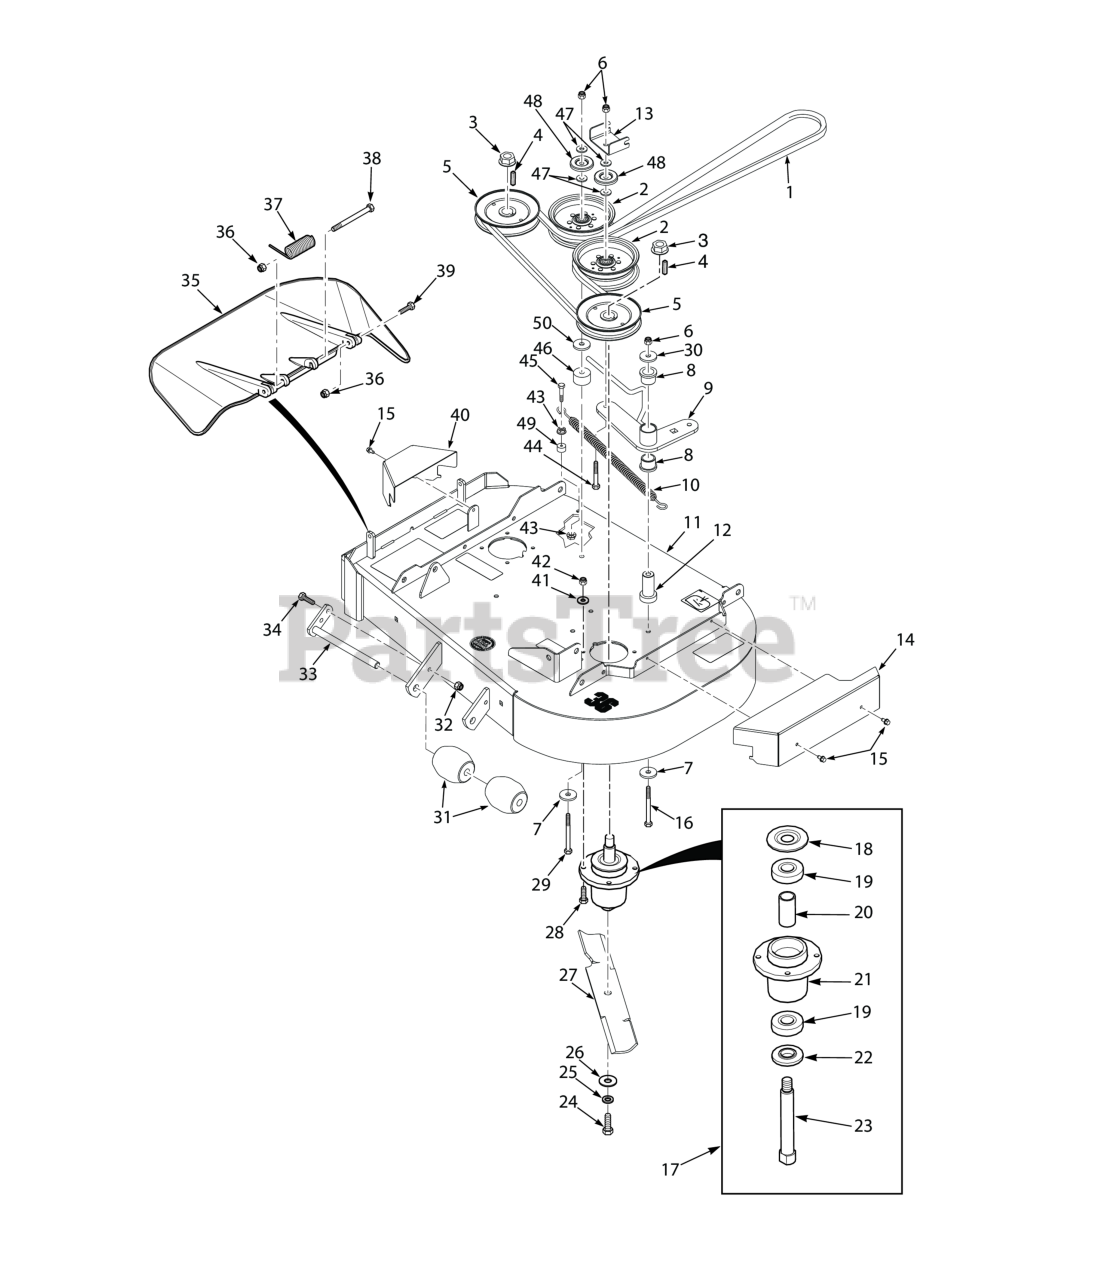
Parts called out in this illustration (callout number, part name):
1	Belt, Cutter Deck
2	Pulley, 5" Idler
3	Nut, 3/4-16 Spriral Lock
4	Key, 1/4 x 1/4 x 1.25" Pulley Mtg.
5	Pulley, 5.73" OD - 25mm Bore
6	HEX NUT, ELASTIC STOP LOCK, 3/8-16
7	Flatwasher, 3/8-.406 x 2.25" x .1875
8	Bearing, Plastic
9	Pivot, Idler
10	Spring, Cutter Deck Idler
11	Cutter Deck w/Decals, SWZT36H
12	Pivot, Idler
13	Bracket, Belt Guide
14	Belt Cover LH SMZL-36
15	Screw, 1/4-20 x .375"
16	Bolt, Hex Head 3/8-16 x 4.00
17	Spindle Assembly
18	Debris Shield
19	Bearing
20	Spacer, Bearing
21	Spindle Housing Assembly
22	Protector, Bearing
23	Shaft, Spindle
24	Bolt, Hex Head 5/8-11 x 1-1/2"
25	Lockwasher, 5/8" Spring
26	Flatwasher, 5/8-.688 x 1-3/4 x .134 HD
27	Cutter Blade, 18" (52V)
28	Bolt, Hex Head 5/16-18 x 1-1/2" Grade 8
29	Bolt, Hex Head, 3/8-16 x 3-1/2"
30	Flatwasher, 3/8-.406 x 1-1-1/2 x 7 Gauge
31	Wheel, Anti-Scalp
32	Nut, Flange Head Elastic Stop 5/16-18
33	Shaft Weldment, Guide Roller
34	Bolt, Heax Head 5/16-18 x 1" (48V / 52V)
35	Discharge Chute Assy. SFZ48
36	HEX NUT, ELASTIC STOP LOCK, 5/16-18
37	Spring, Discharge Chute
38	Bolt, 5/16-18 x 4-3/4" Hex Head
39	Bolt, Hex Head 5/16-18 x 1-1/2" - Front
40	Belt Cover, RH SMZL-36
41	Lockwasher, 5/16 (.317 x .586 x .078) Helical Spring
42	Lock Nut, 5/16-18 Elastic Stop Grade 8
43	NUT, 3/8-16 SERRATED FLANGE HEX HEAD
44	Capscrew, Hex Head 3/8-16 x 2-1/2"
45	Bolt, Hex Head 3/8-16 x 1-1/2" Grade 8 Black
46	Spacer, Idler Pulley
47	Flatwasher, 3/8 (.391 x .938 x .105 HD) Grade 8
48	Quick Pin, 5/16" Dia.
49	SPACER, IDLER
50	Flat washer, 1/4-.266 x .875 x .125
